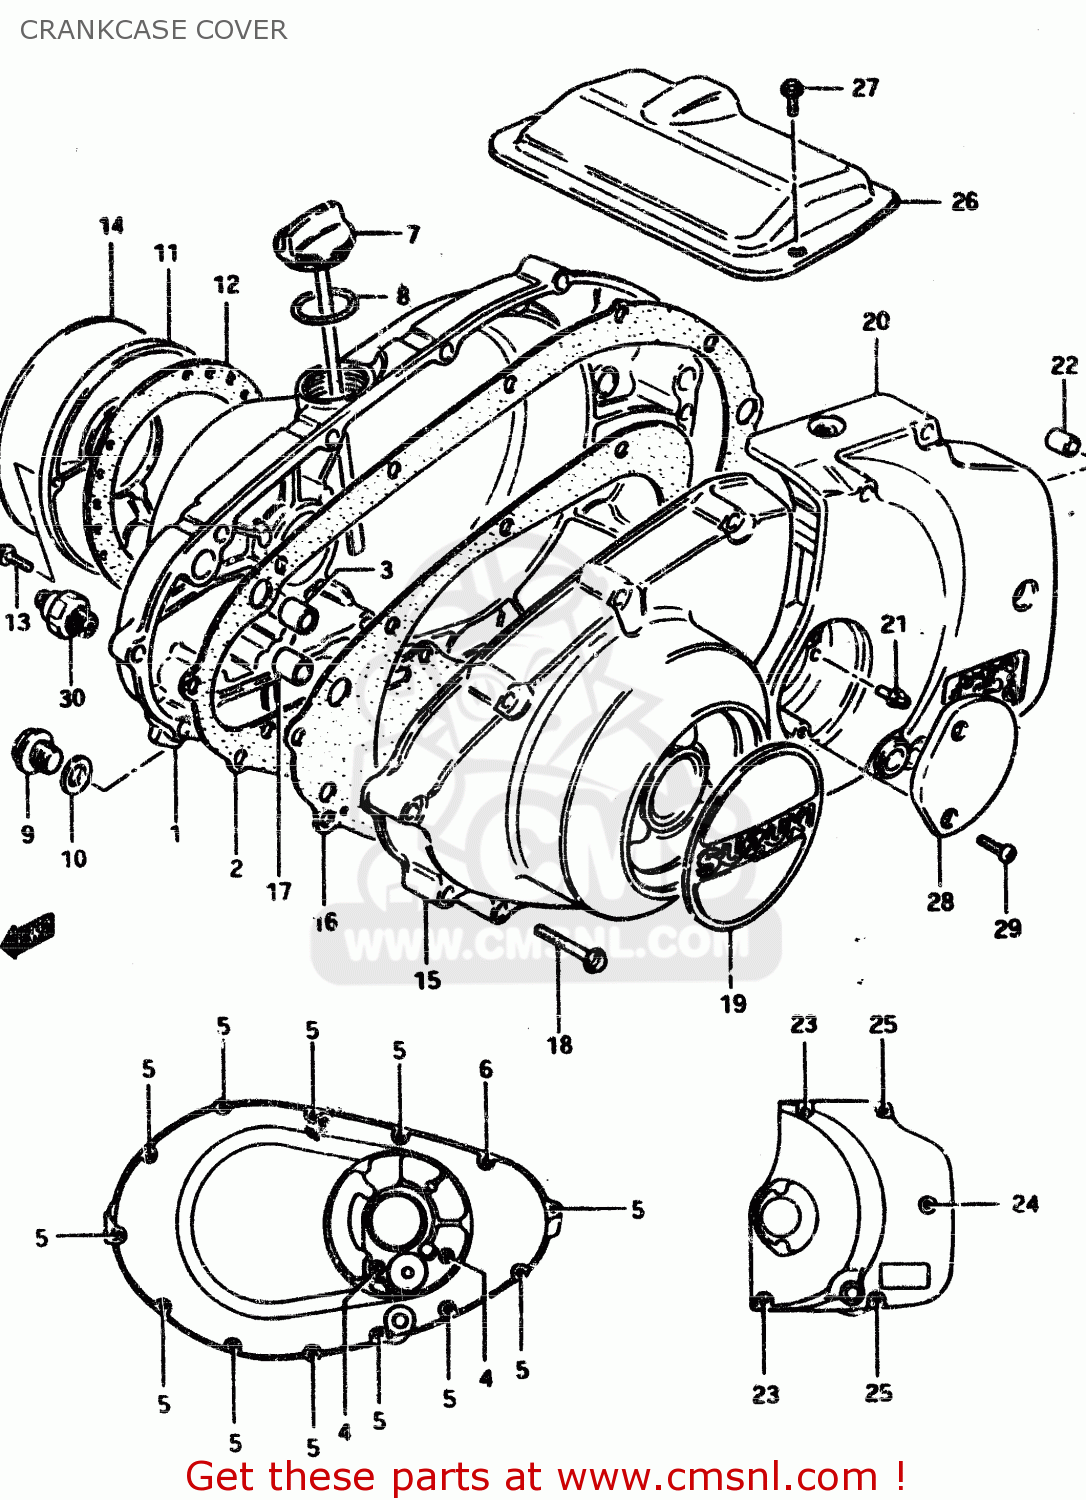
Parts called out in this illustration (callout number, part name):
1	COVER,CLUTCH
2	GASKET,CLUTCH COVER (MCA)
3	PIN
4	BOLT (6X35)
5	BOLT (6X35)
6	BOLT
7	GAUGE,OIL LEVEL
8	O-RING
9	PLUG (14X12)
10	GASKET(14X19.2X2) (NAS)
11	COVER,CONTACT BREAKER
12	GASKET,CONTACT BREAKER COVER (NAS)
13	BOLT 5X16
14	EMBLEM,MAGNETO COVER
15	COVER,MAGNETO
16	GASKET,MAGNETO COVER (MCA)
17	PIN
18	BOLT (6X35)
19	EMBLEM,MAGNETO COVER
20	COVER,ENGINE SPROCKET
21	NIPPLE
22	PIN
23	BOLT (6X65)
24	BOLT (6X50)
25	BOLT (6X40)
26	COVER,STARTER MOTOR
27	BOLT (5X8)
28	CAP, CLUTCH RELEASE
29	SWITCH ASSEMBLY
30	SWITCH ASSEMBLY
